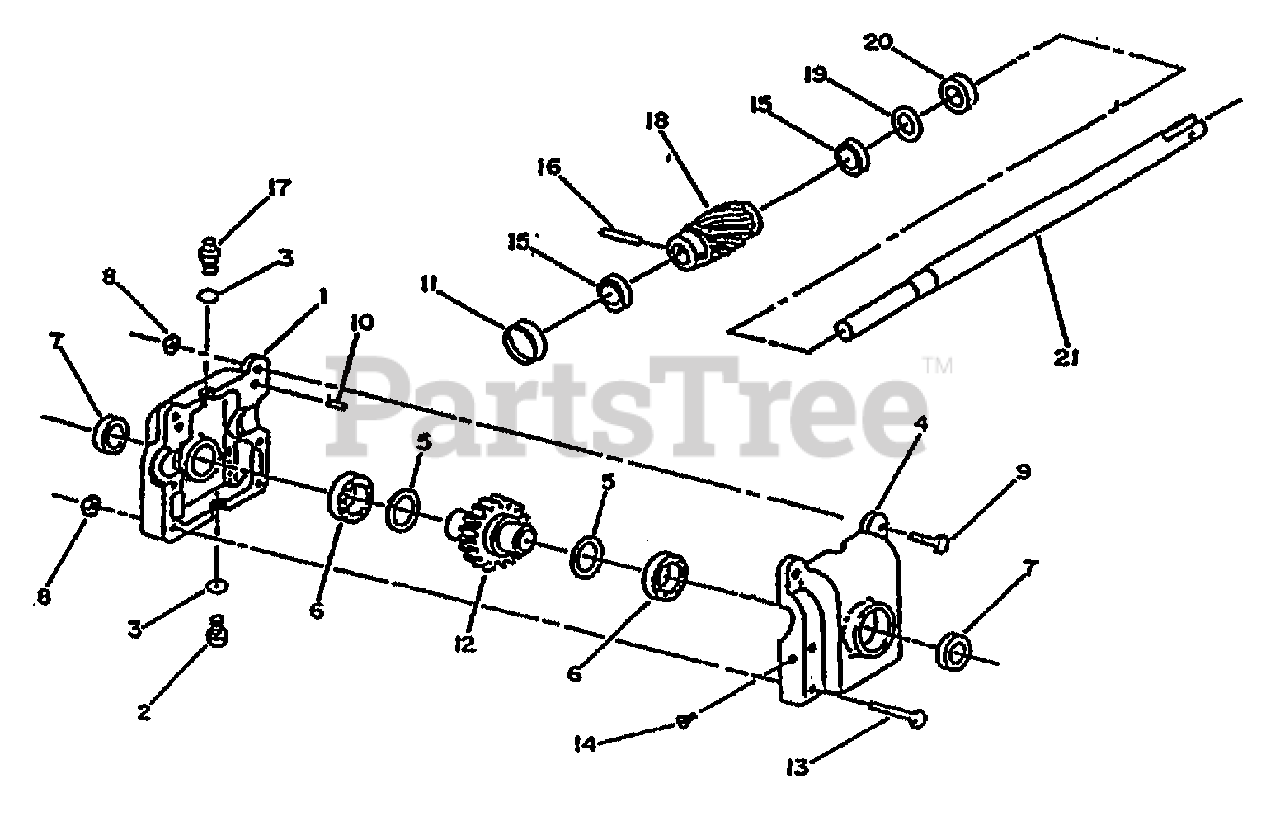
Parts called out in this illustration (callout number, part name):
1	HSG-GEARCASE
3	UD RING-O
4	HSG-GEARCASE
6	BRG
8	NUT-M8 P1.25
9	BOLT M8X40
13	BOLT M8X60
14	PLUG-SQ HEAD 1/4-18 NPT
16	PIN-SPRING
17	PLUG-PIPE
18	PINION
19	SHIM-WASHER
